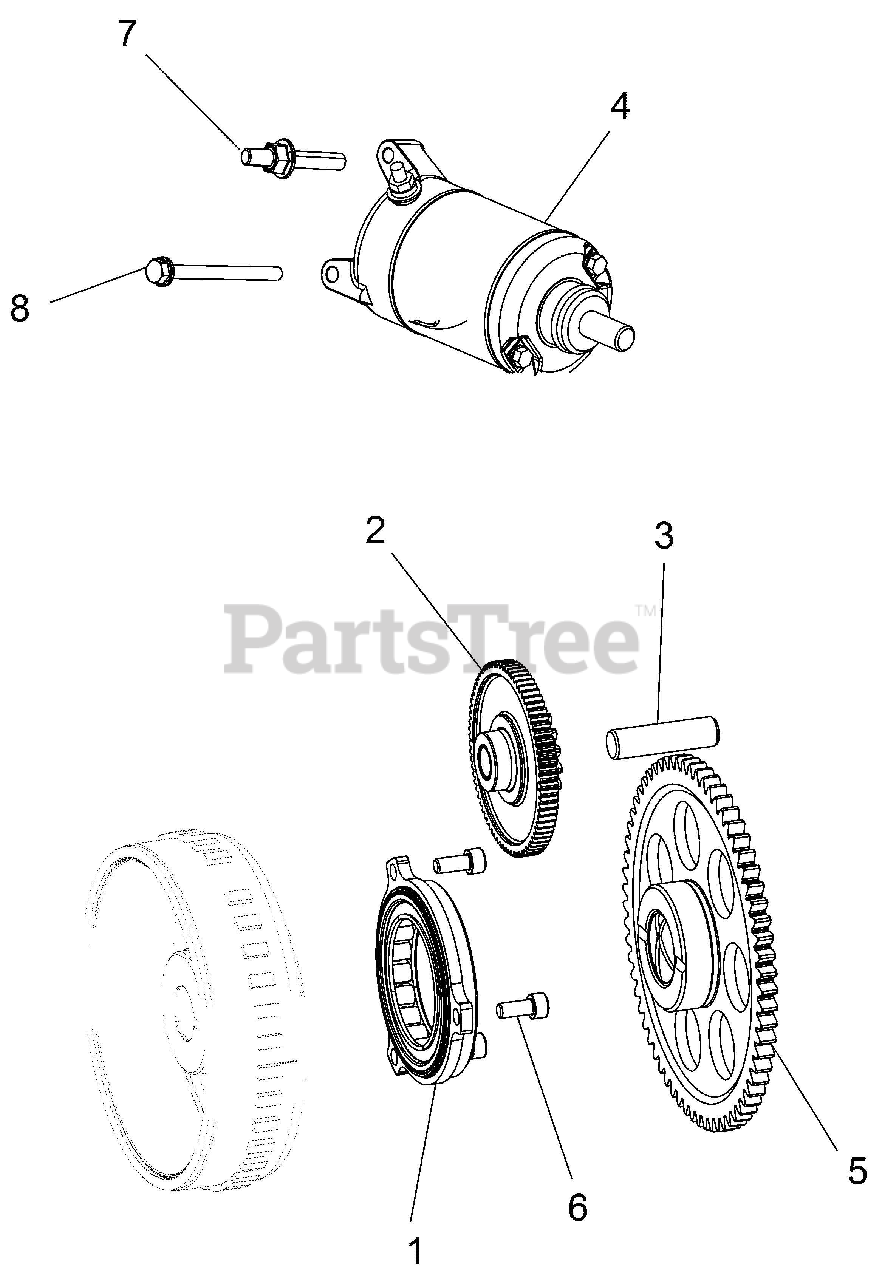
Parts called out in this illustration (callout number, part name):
1	ASM-SPRAG CLUTCH,HUB,STARTER
2	ASM-GEAR,STARTER
3	PIN-SOLID,STARTER TQ LIMITGEAR
4	STARTER,1-CYL
5	GEAR-FREEWHEEL,1WAY CLUTCH
7	STUD-DOUBLE,END,M6X1.0X25/10
8	SCR-M6X1X75 HX/FL
